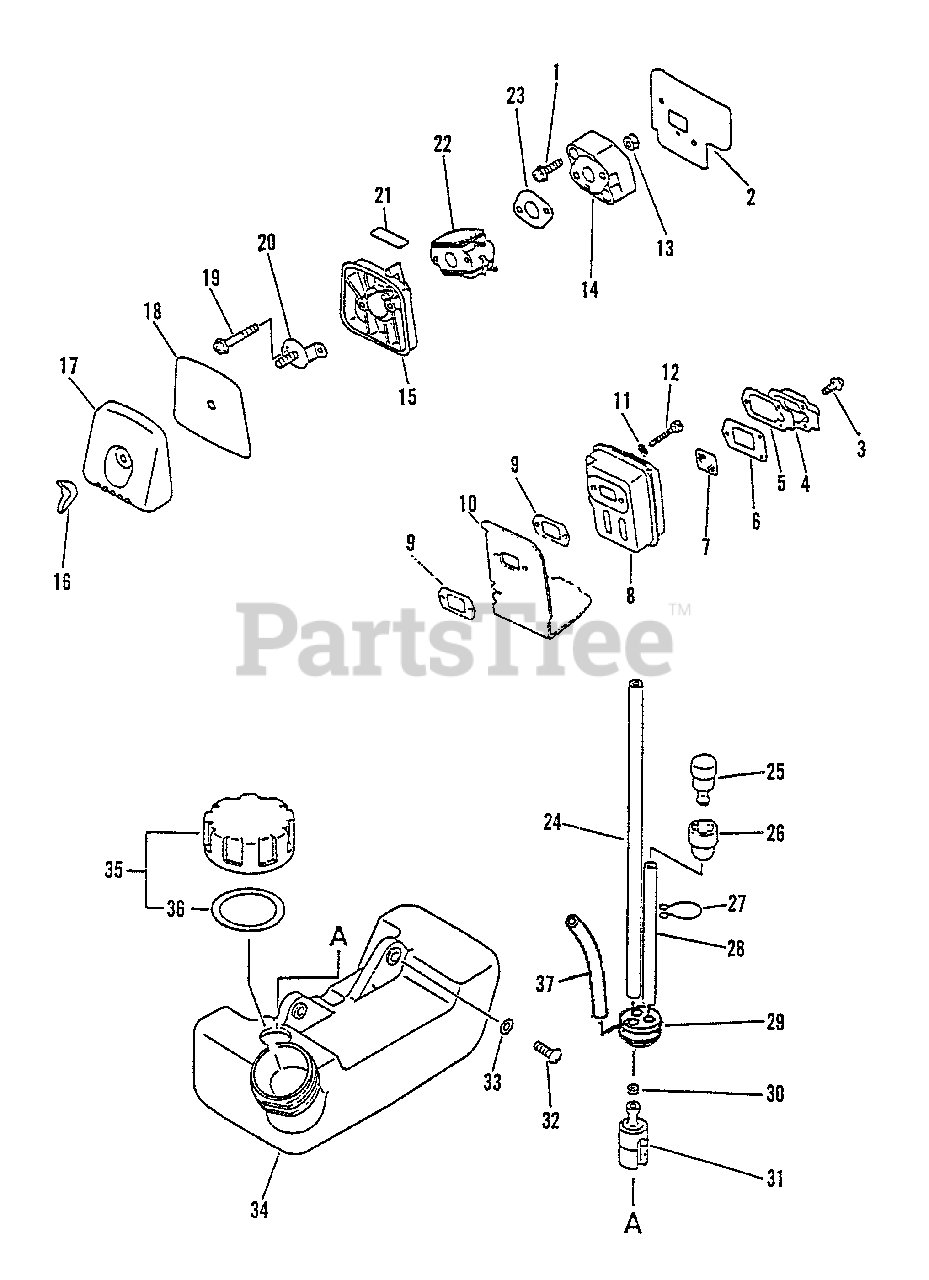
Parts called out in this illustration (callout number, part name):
1	SCREW - 5X22
2	GASKET, INTAKE
3	SCREW - 4X10
4	GASKET, EXHAUST - INNER
5	GUIDE, EXHAUST - INNER
6	GASKET, EXHAUST
7	SCREEN, SPARK ARRESTOR
9	GASKET, EXHAUST
10	SHIELD, EXHAUST
11	WASHER - 5
12	SCREW - 5X55
14	INSULATOR, INTAKE
15	AIR FILTER CASE KIT - BLACK
16	WINGNUT - 6
17	COVER, AIR FILTER - BLACK
18	FILTER, AIR
19	SCREW - 5X64
20	PLATE, PREVENT
21	LABEL - CHOKE
22	CARBURETOR C1U-K26
23	GASKET, INTAKE
24	PIPE - 3X5X180 -- BLACK
25	VENT, FUEL TANK
26	COVER, VENT
28	PIPE - 3X6X70 -- CLEAR
29	GROMMET
30	CLIP - 6
31	FILTER, FUEL
32	SCREW - 5X16
33	WASHER - 5
34	TANK, FUEL
35	CAP ASSY
36	GASKET, CAP
37	PIPE - 3X6X90 -- CLEAR
